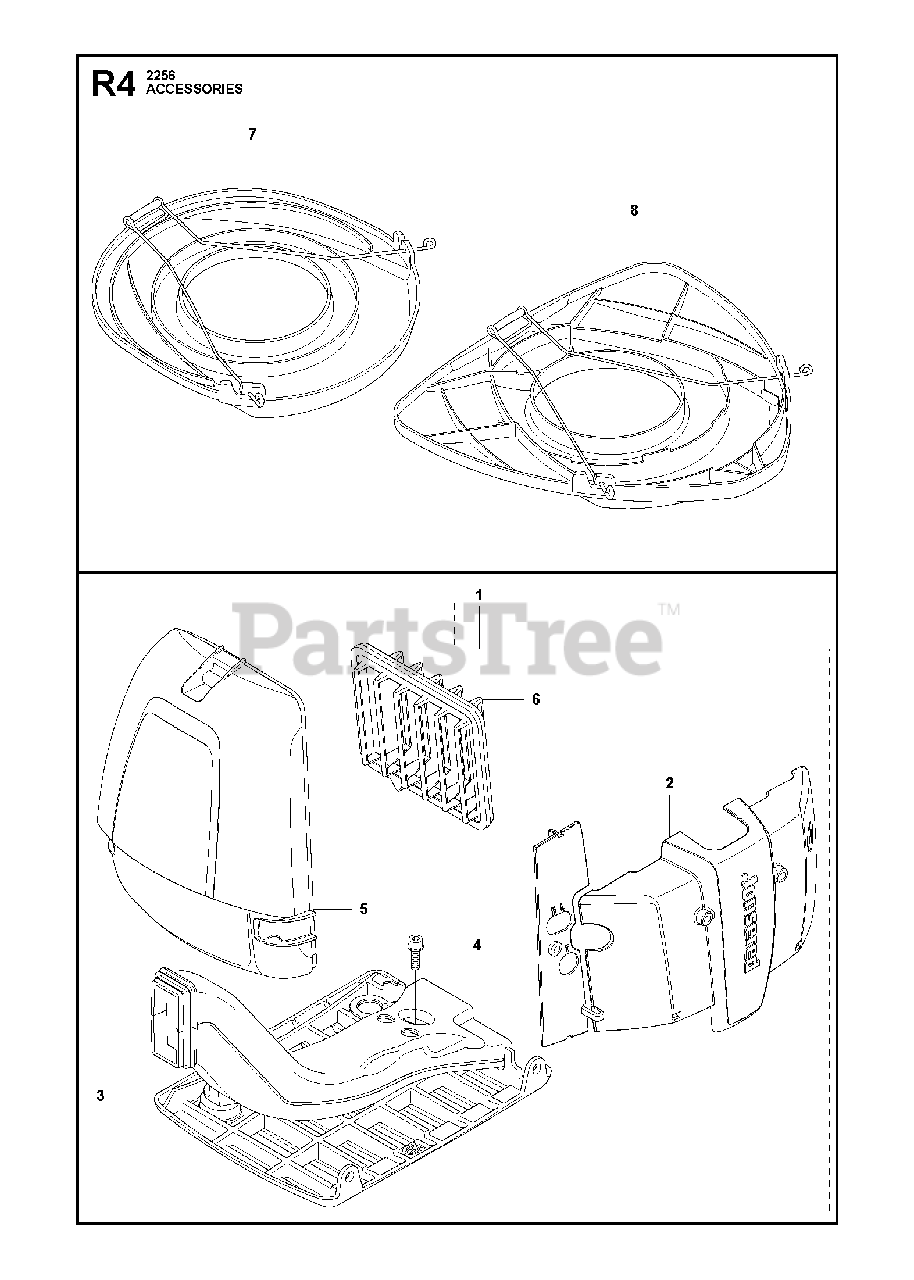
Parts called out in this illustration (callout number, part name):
3	AIR DUCT
4	SCREW
6	FILTER
7	BLADE GUARD TRANSPORT
8	TRANSPORT GUARD
